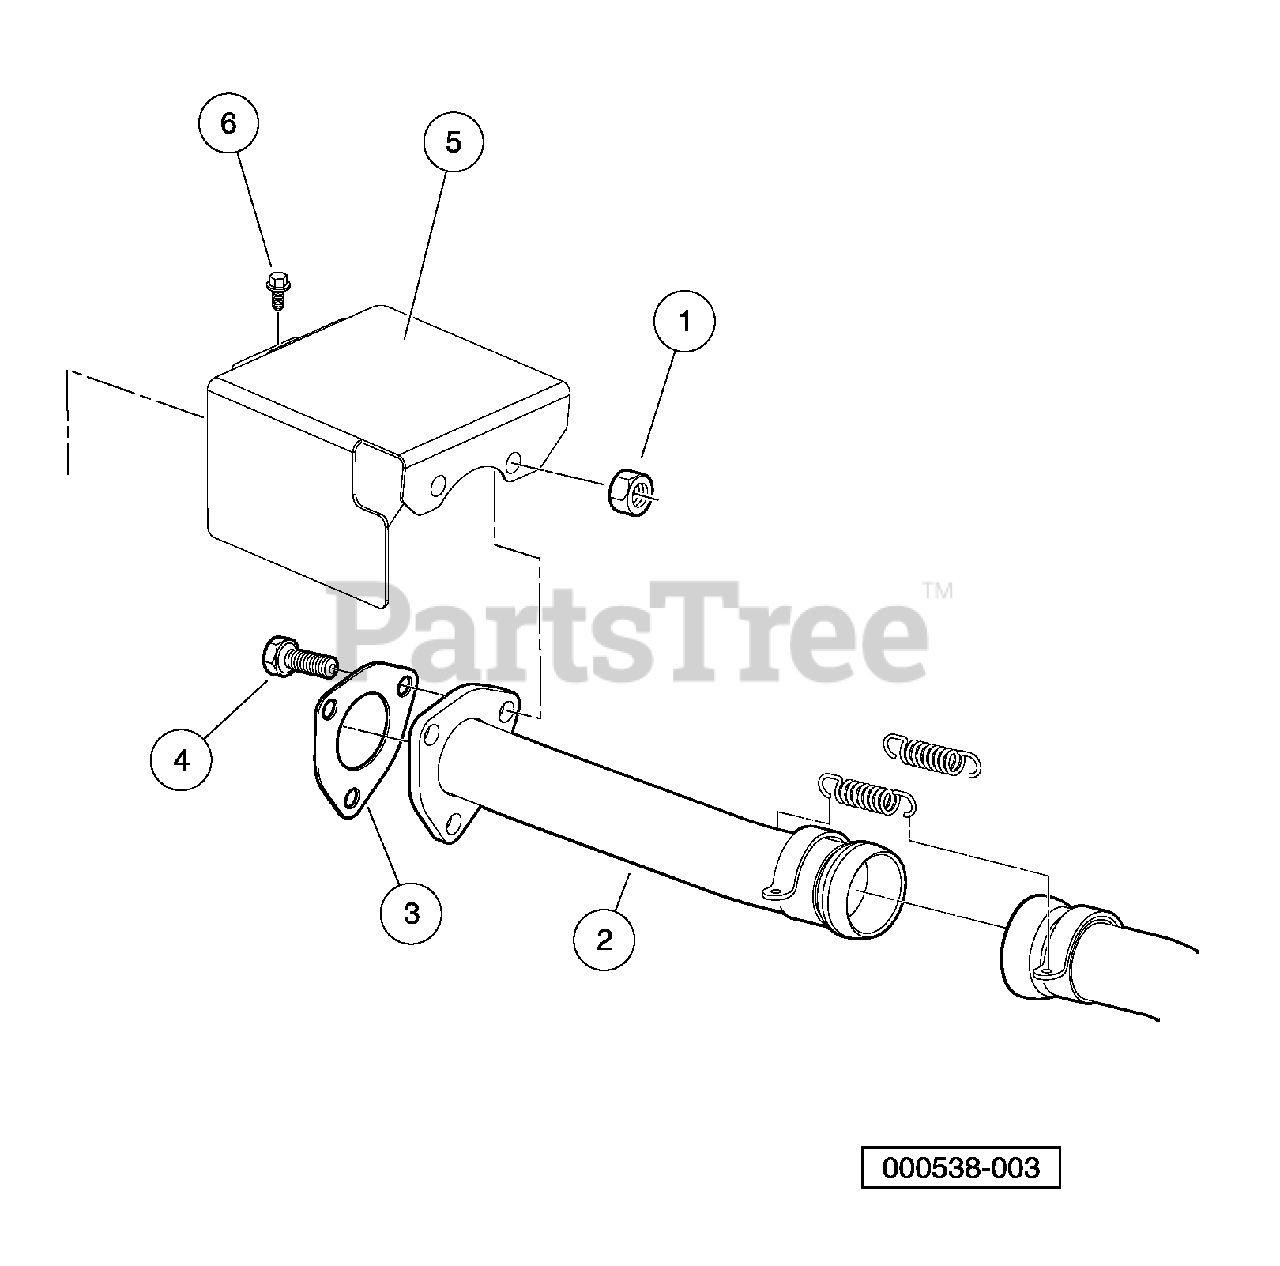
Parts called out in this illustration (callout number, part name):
1	Nut,m8,all Metal Lock
2	Pipe, Exhaust Diesel Main
3	Gasket, Exhaust Diesel
4	Bolt, M8 X 1.25 X 40 with Loctite
5	Shield, Diesel Exhaust
6	Bolt, D722, Exhst Manfld Cover
